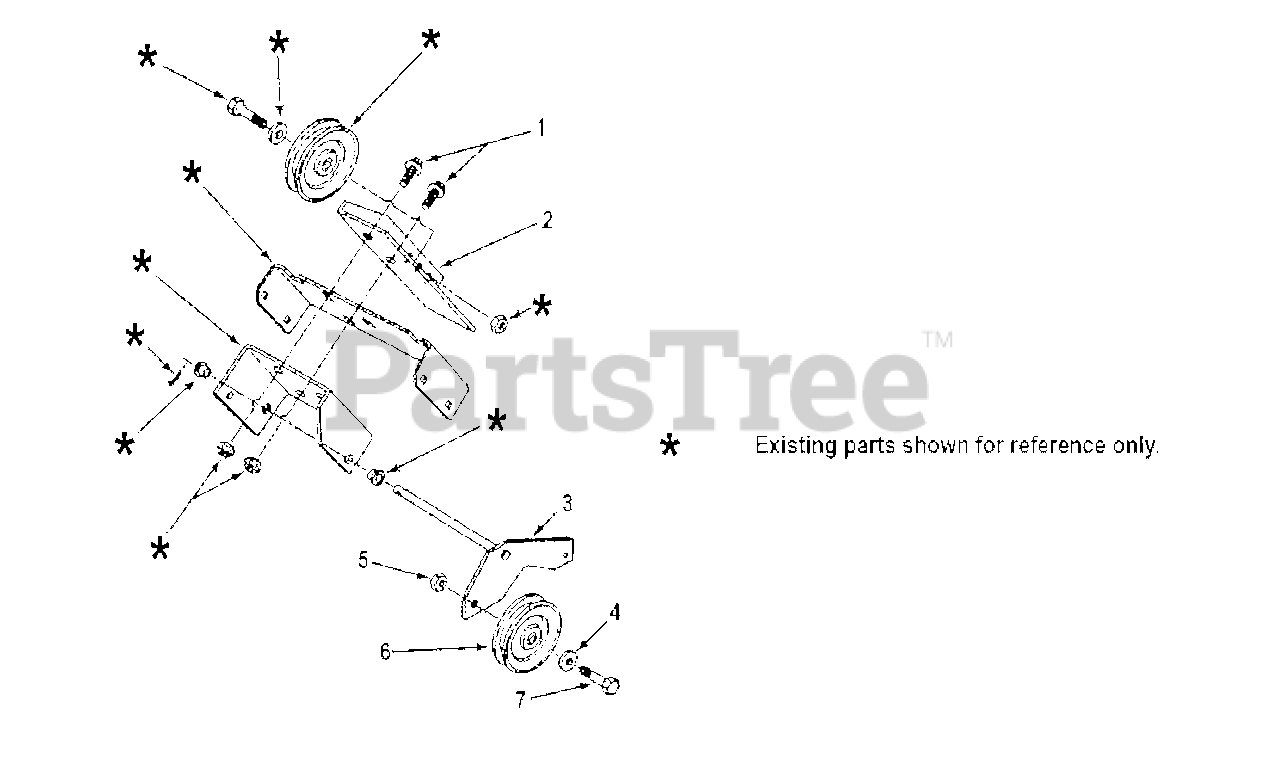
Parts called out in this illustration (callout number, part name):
1	BOLT, Hex Flage Lock 3/8-16x1 1/4"
2	BRACKET, Idler Take Up
3	STRUCTURE, Idler Arm
4	WASHER, Flat
5	NUT, Hex Lock 3/8-16 YZ
6	PULLEY, Idler "V" 3.56" O.D.
7	BOLT, Hex 3/8-16x1 1/2" GR 5 YZ
